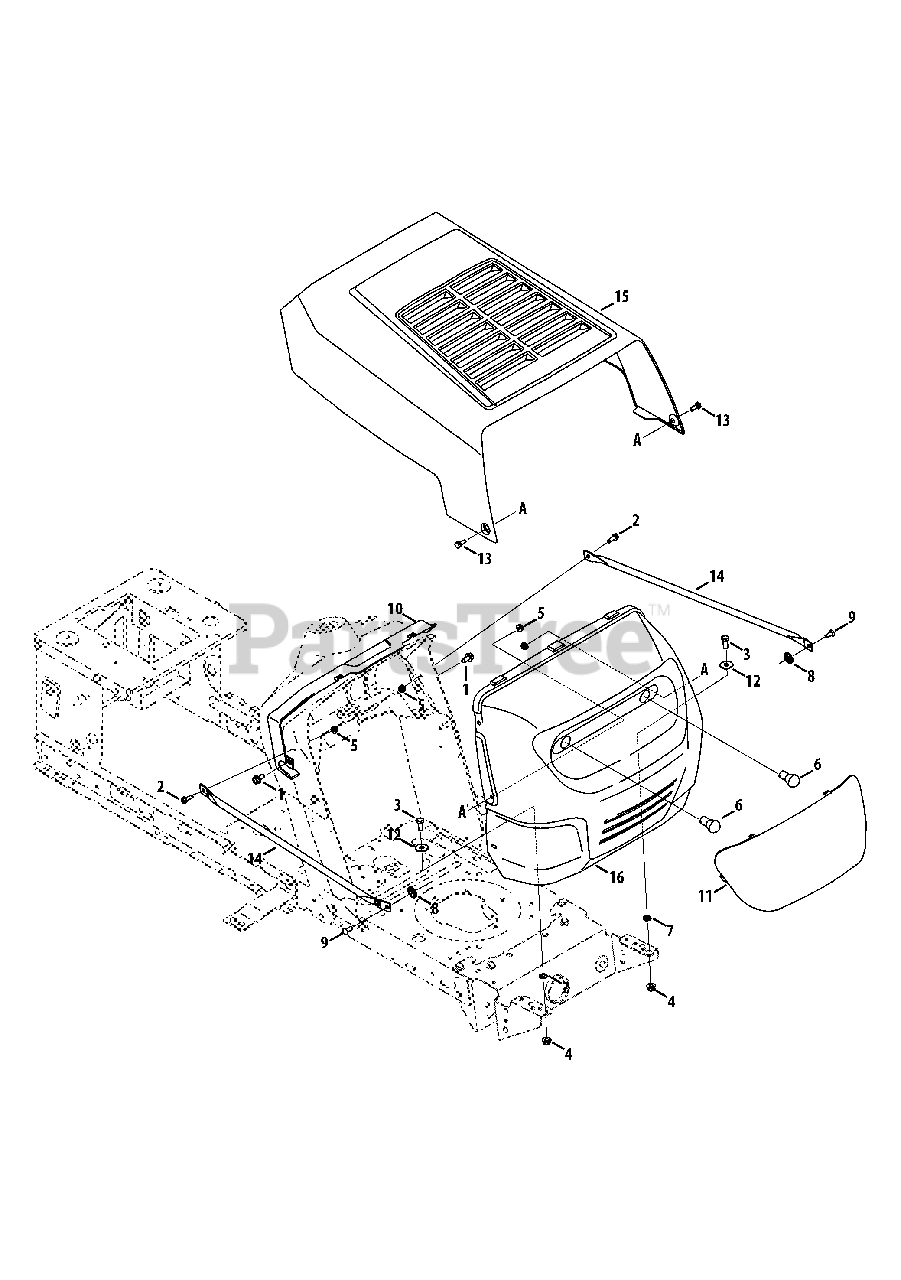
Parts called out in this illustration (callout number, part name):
1	Screw, 1/4-15 x .750
2	Screw, 1/4-20 x .750
3	Hex Screw, 5/16-18 x .75
4	Flangelock Nut, 5/16-18
5	Flangelock Nut, 1/4-20
6	Miniature Lamp 12V Socket
7	Speed Nut, .3125
8	Push-On Nut, .25
9	Flat Head Rivet, 1/4"
12	Flat Washer, .344 x 1.0 x .063
13	Shoulder Bolt, 1/4-20 x .375 x .125
14	Grill Support Rod
16	Grill
